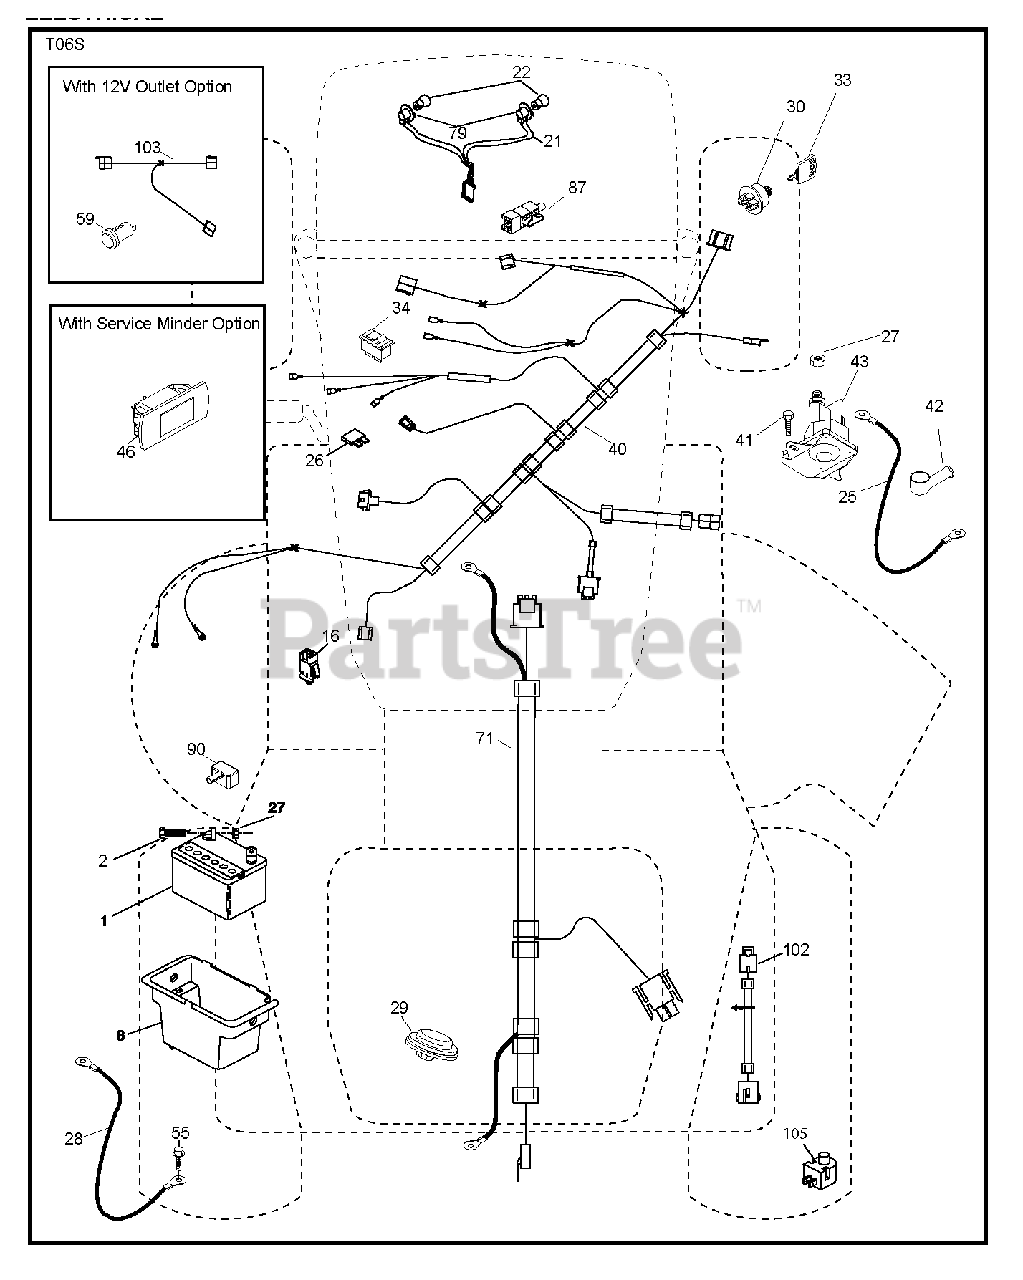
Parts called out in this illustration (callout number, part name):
1	Battery, Dry 30 Amp
2	BOLT.HEX.1/4.X.3/4.DICHROMATE
8	BOX.BATTERY.MNT.REAR.L
16	SWITCH INTERLOOK PUSH-IN
21	HARNESS.LIGHT W/4152J BULBS
25	CABLE.STARTER.6G.BL/RED.17.5
26	FUSE 20AMP
27	NUT
28	CABLE.BLACK.18"REAR.BA
29	SWITCH.SEAT.DELTA.OPC.
30	SWITCH.IGN.DELTA.W.LGH.ROS
33	KEY.CHAIN.BLISTER.PACK.GEN.USA
40	HARNESS IGN. DASH
41	SCREW
42	TERMINAL COVER
43	SOLENOID.W/BRASS.PLUNGER
46	RP GUAGE.SRVCMNDR.HRMTR.
55	SCREW 5/16"
71	HARNESS.IGN.CHASS.TEX.REAR.BAT
79	BULB HOLDER ASM.
87	SWITCH.INTRLCK.CLUTCH.
90	COVER.TERMINAL.BATTERY
102	HARNESS PIGTAIL PCH TEX ROS
105	REVERSE SWITCH
